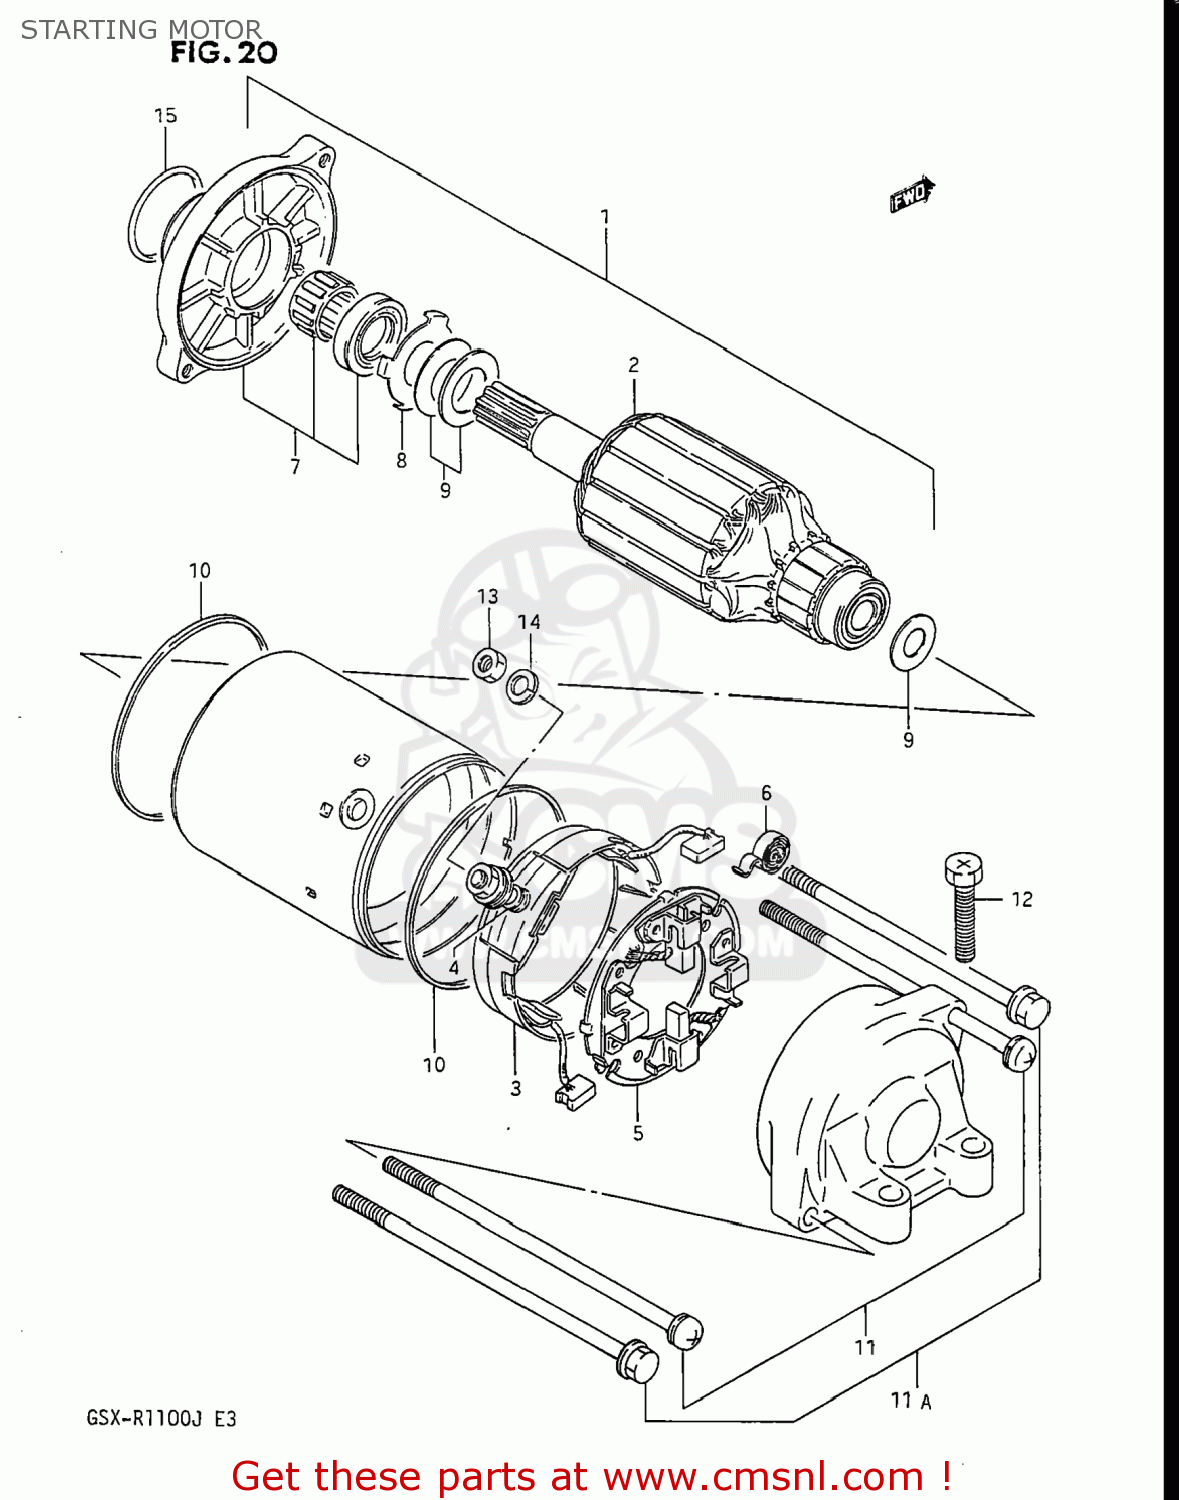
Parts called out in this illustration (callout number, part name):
1	MOTOR ASSEMBLY,STARTING
2	ARMATURE
3	TERMINAL SET,BRUSH,PLUS
4	O RING
5	HOLDER SET,BRUSH(-)
6	SPRING,BRUSH
7	BRACKET SET,STARTING MOTOR
8	SHIM SET
9	SHIM SET
10	SEAL,RING
11	BOLT
11A	BOLT SET
12	SCREW (6X25)
13	NUT
14	WASHER,LOCK
15	O RING(D:3,ID:24.5)
